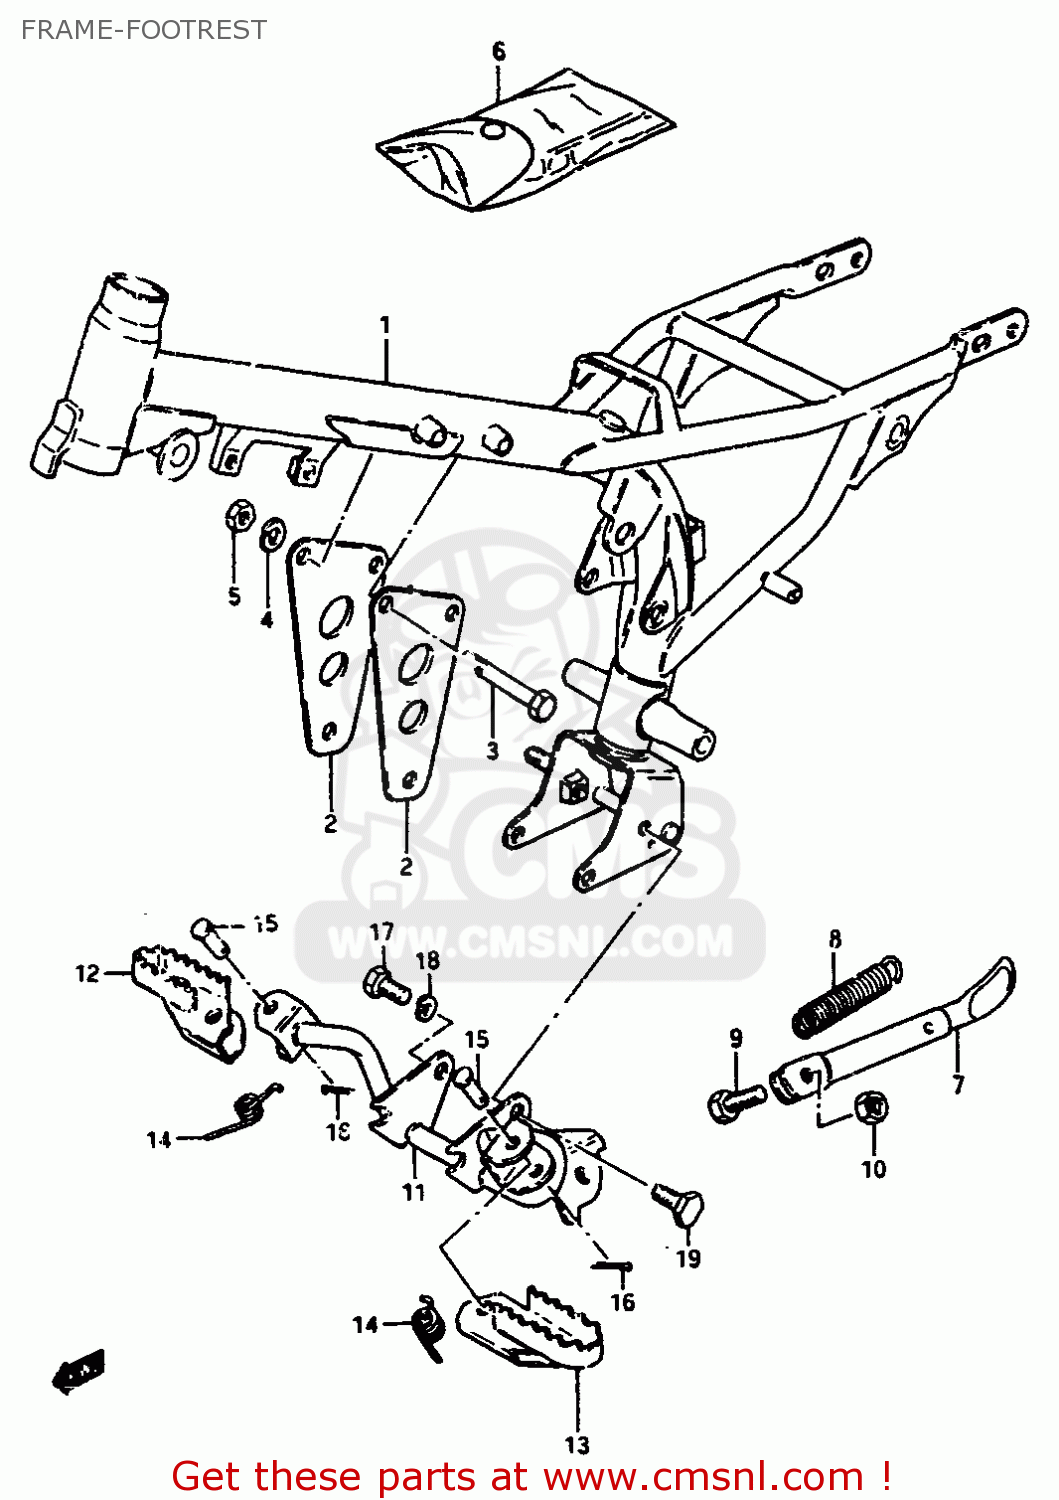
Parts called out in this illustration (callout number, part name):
1	FRAME
2	PLATE,ENG MTG
3	BOLT
4	LOCK WASHER
5	NUT
6	TOOL SET
7	STAND,PROP
8	SPRING
9	BOLT 8X22
10	NUT
11	BAR,FR FOOTREST
12	FOOTREST,FRONT,RIGHT
13	FOOTREST,FRONT,LEFT
14	SPRING
15	PIN
16	PIN 20X20
17	BOLT,8X16
18	LOCK WASHER
19	BOLT(8X14)
